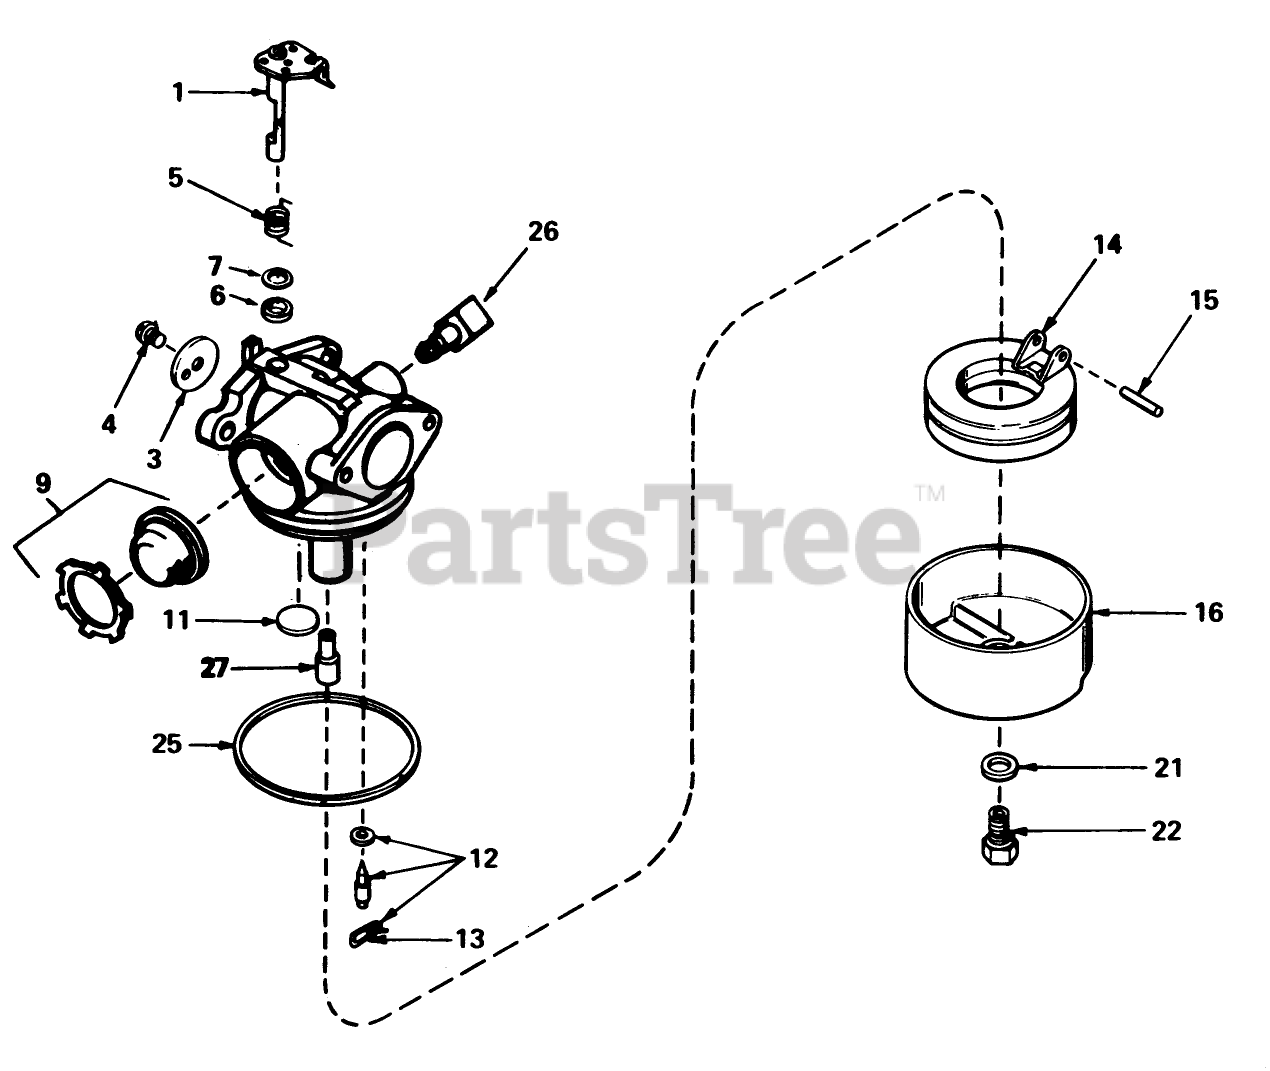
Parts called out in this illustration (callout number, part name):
1	Throttle Shaft and Lever ASM
3	Throttle-Shutter
4	Screw-Shutter
5	Spring-Return, Throttle
6	Seal-Dust
7	Washer-Seal, Dust
9	Primer Assy.
11	Plug-Welch, Atmospheric Vent
12	Inlet Needle, Seat Clip Assy. (Incl. No. 13)
13	Clip-Spring
14	Float
15	Shaft-Float
16	Bowl Float
21	Gasket-Bowl
22	Nut-Float Bowl
25	O Ring-Bowl, Float
26	Fitting-Fuel
27	Spacer
